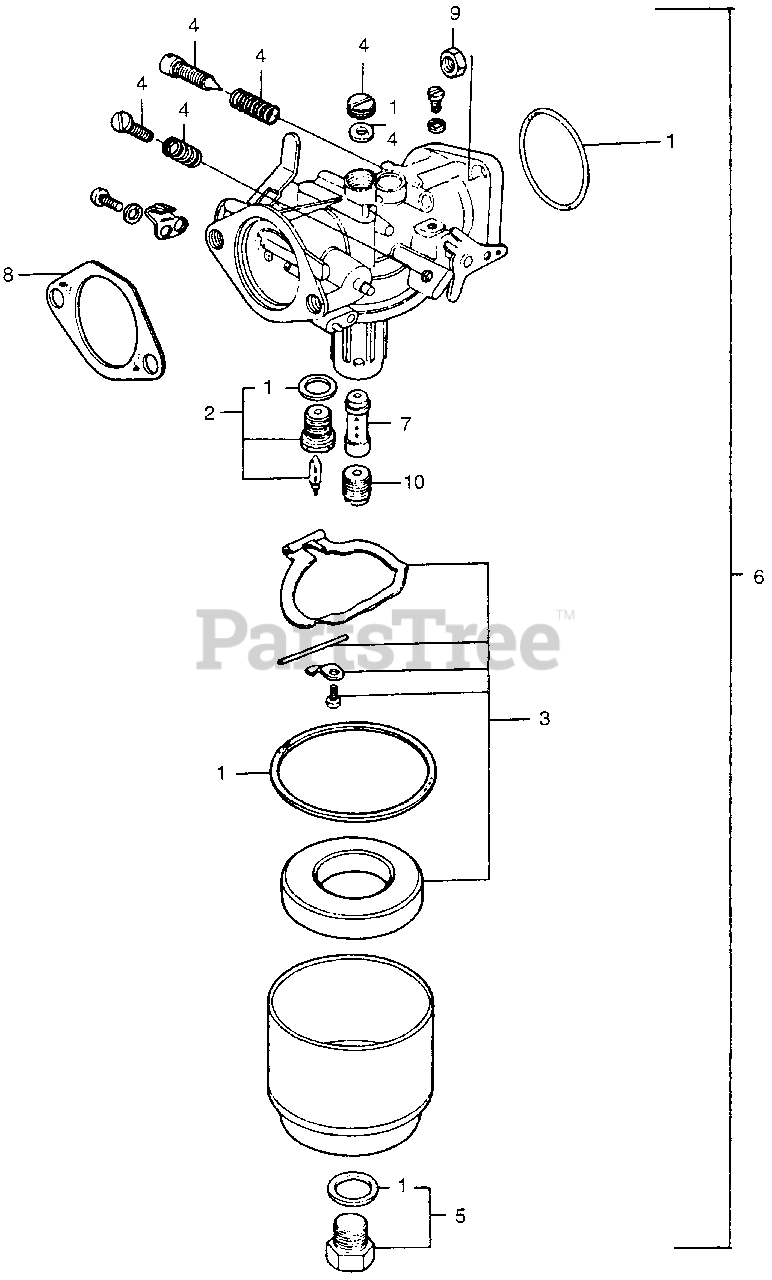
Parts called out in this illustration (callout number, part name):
1	GASKET SET
2	VALVE SET, FLOAT
3	FLOAT SET (NOT AVAILABLE)
4	SCREW SET A (NOT AVAILABLE)
5	SCREW SET (NOT AVAILABLE)
6	CARBURETOR ASSY. (N/A: SEE COMPONENTS)
7	NOZZLE, MAIN (NOT AVAILABLE)
8	GASKET, AIR CLEANER (NOT AVAILABLE)
9	NUT, HEX. (6MM)
10	JET, MAIN (#72) (NOT AVAILABLE)
10	JET, MAIN (#75) (NOT AVAILABLE)
10	JET, MAIN (#78)
10	JET, MAIN (#80) (NOT AVAILABLE)
10	JET, MAIN (#82) (NOT AVAILABLE)
